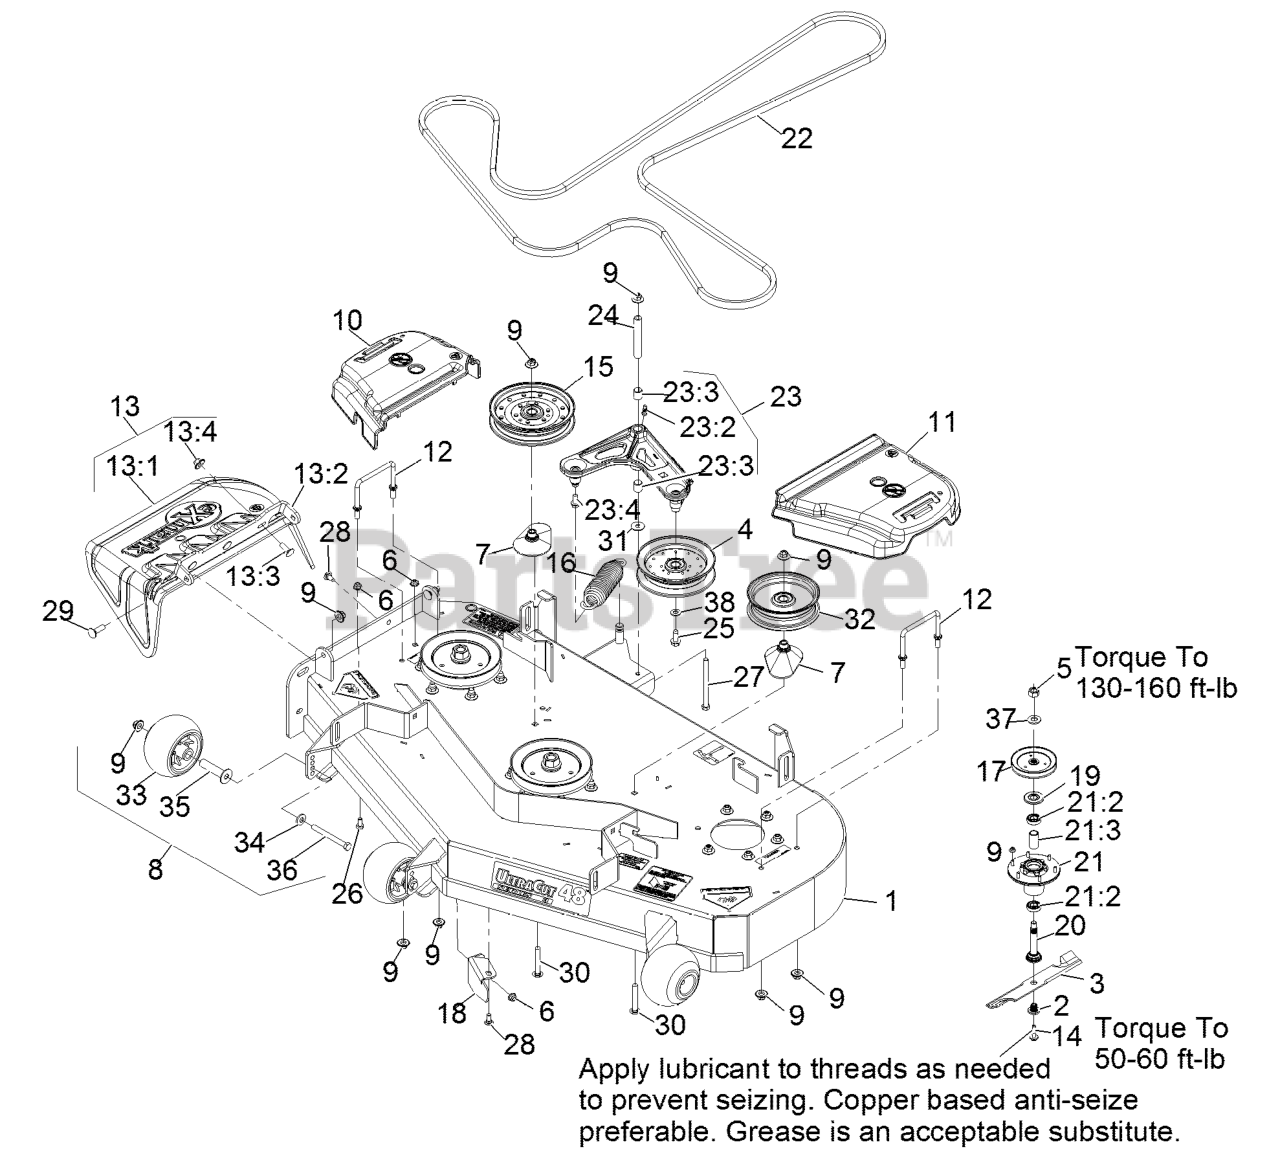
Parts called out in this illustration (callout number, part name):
1	ASM-DECK W/DECALS 48
2	BUSHING,SPLINED
5	NUT-HEX
6	NUT-HF, NI
7	SPACER-PULLEY
8	KIT, ANTI-SCALP ROLLER
9	Nut-Nyloc 3/8-16 Flg
10	COVER-BELT, RH
11	COVER-BELT, LH
12	WIREFORM-COVER
13	ASM,DISCHARGE CHUTE
13:1	CHUTE,DISCHARGE
13:2	BRACKET,DISCHARGE CHUTE
13:3	SCREW-CARR
13:4	Nut-Nyloc 3/8-16 Flg
14	SCREW,SEMS 1/2-20 X 2.19
16	SPRING-EXTENSION
17	SHEAVE,BLADE DRIVE 5.90
18	BAFFLE,DISCHARGE 483
19	GUARD,BEARING TOP .989
20	ASM-SPINDLE AND SEAL
21	ASM-CUTTER HSG WITH BEARINGS
21:2	BEARING-BALL
21:3	SPACER-BEARING
22	BELT-B154.88
23	IDLER ARM ASM
23:2	FITTING-GREASE, 90 DEG
23:3	SLEEVE-BEARING
23:4	SCREW-THD ROLL, HWH
24	BUSHING
25	SCREW-FORMING, THREAD
26	SCREW-HH
27	SCREW-HH
28	BOLT-CARR
29	BOLT-CARR
30	SCREW-CARR
32	IDLER-PULLEY, FLAT
33	ROLLER-SCALP, ANTI
34	WASHER-BELLEVILLE
35	AXLE, ROLLER
36	SCREW-HH 3/8-16 X 3 3/4 GR 8
38	WASHER-FLAT
